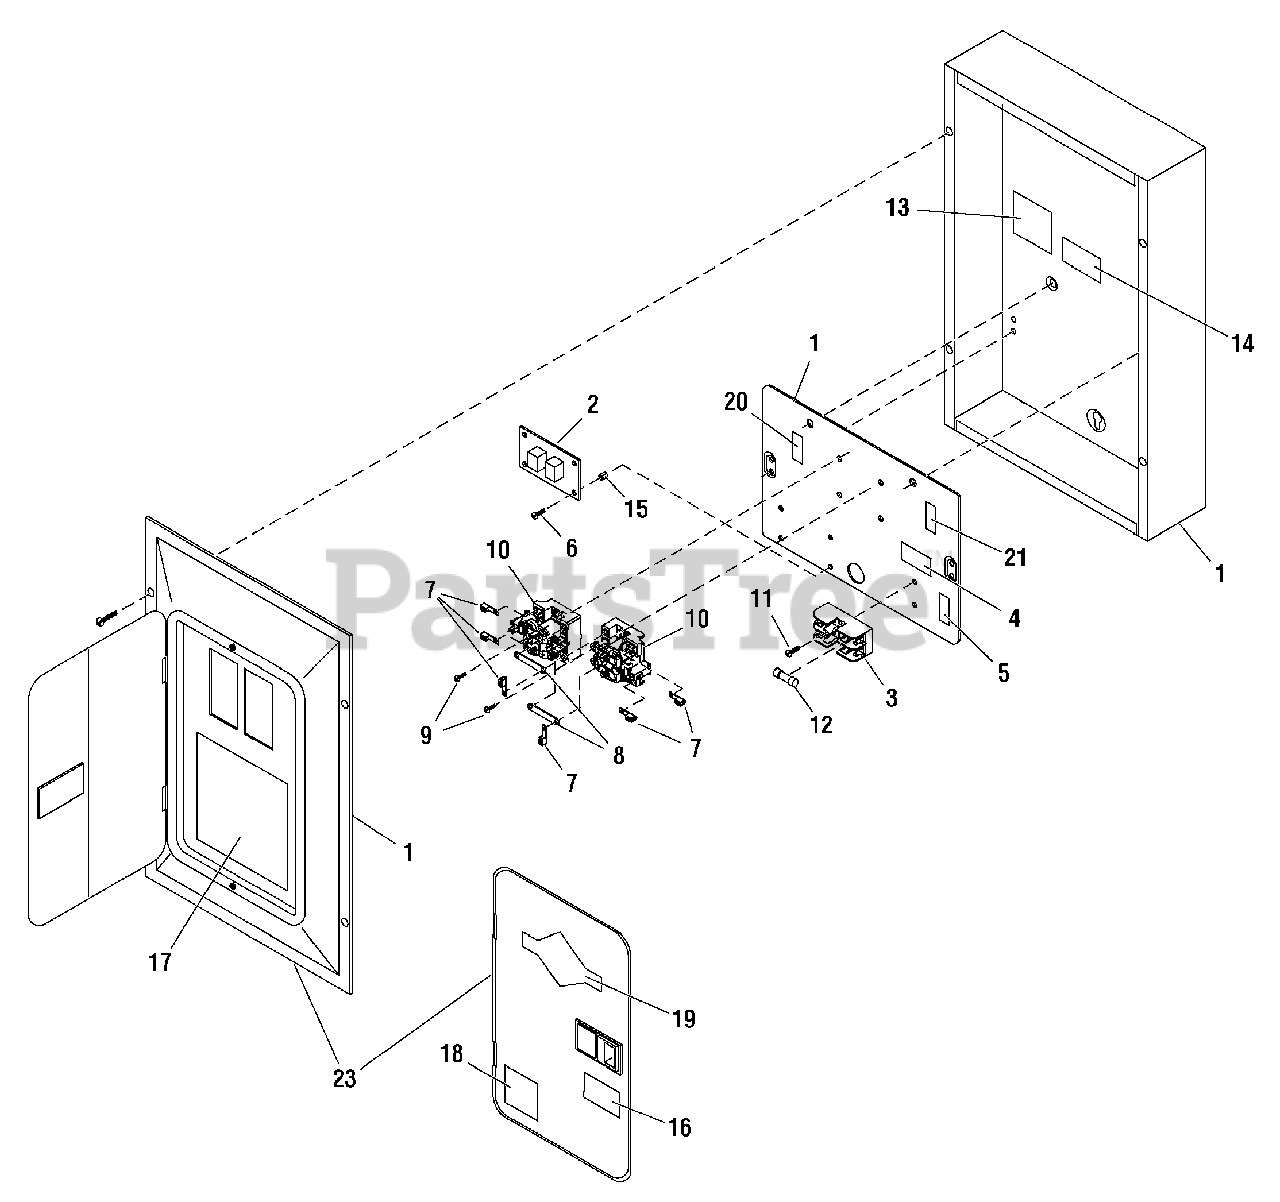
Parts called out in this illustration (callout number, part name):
1	LOADCENTER
5	DECAL
7	TERMINAL
23	COVER, Load Center
